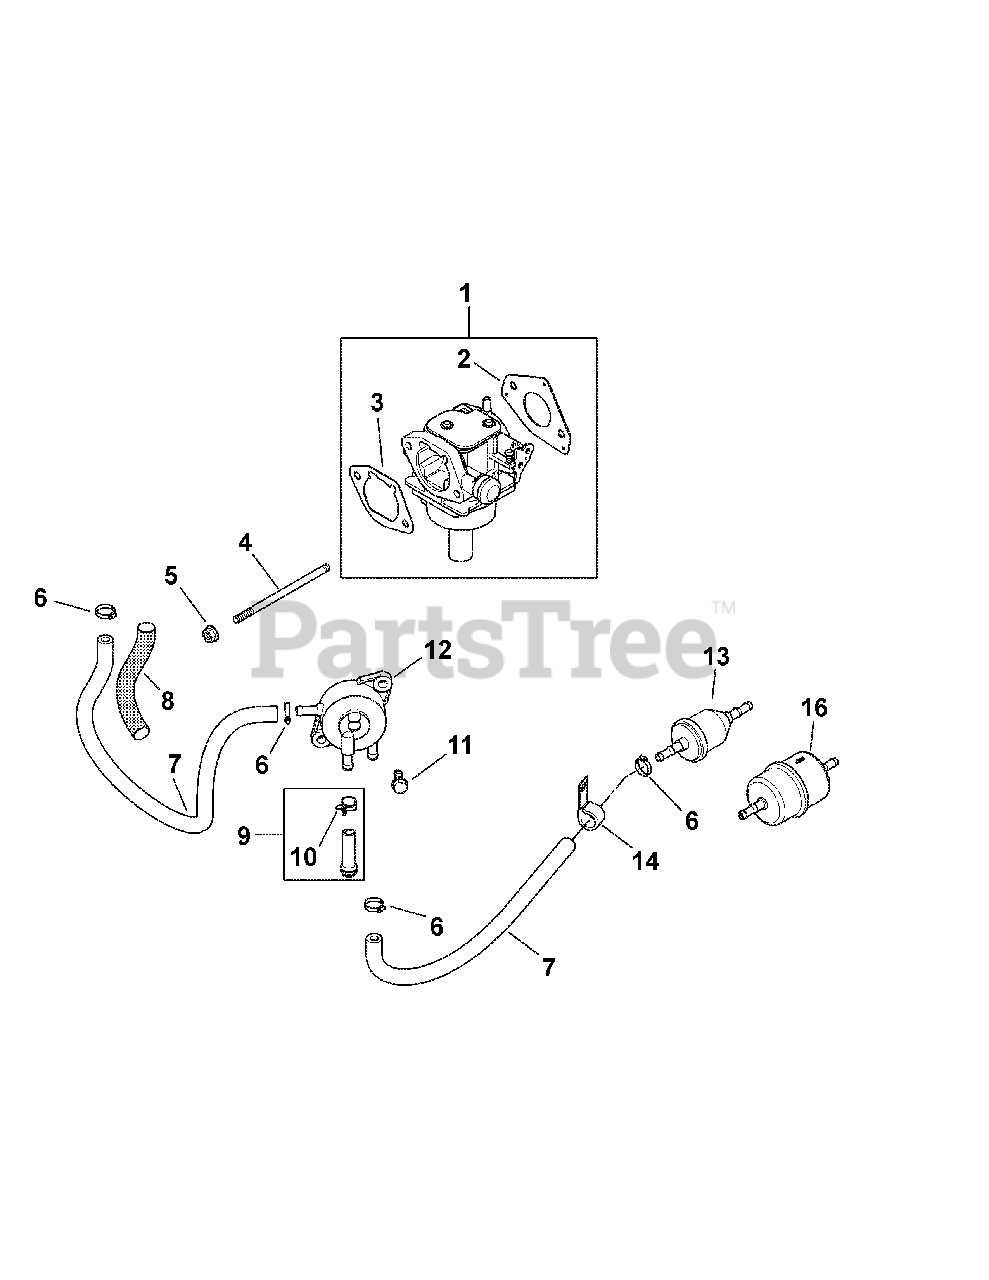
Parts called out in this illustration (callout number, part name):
1	Carburetor Kit, 22mm KEIHIN
2	Carburetor Gasket
3	Air Cleaner Base Gasket
4	Stud, M6 x 1.0 x 106
5	Flg. Nut, M6 x 1.0
6	Hose Clamp, 1/2
7	Fuel Line
8	Fuse Block
10	Fuse Block
11	Tap Screw, M6 x 1.7 x 18
13	Fuel Filter
16	Fuse Block
